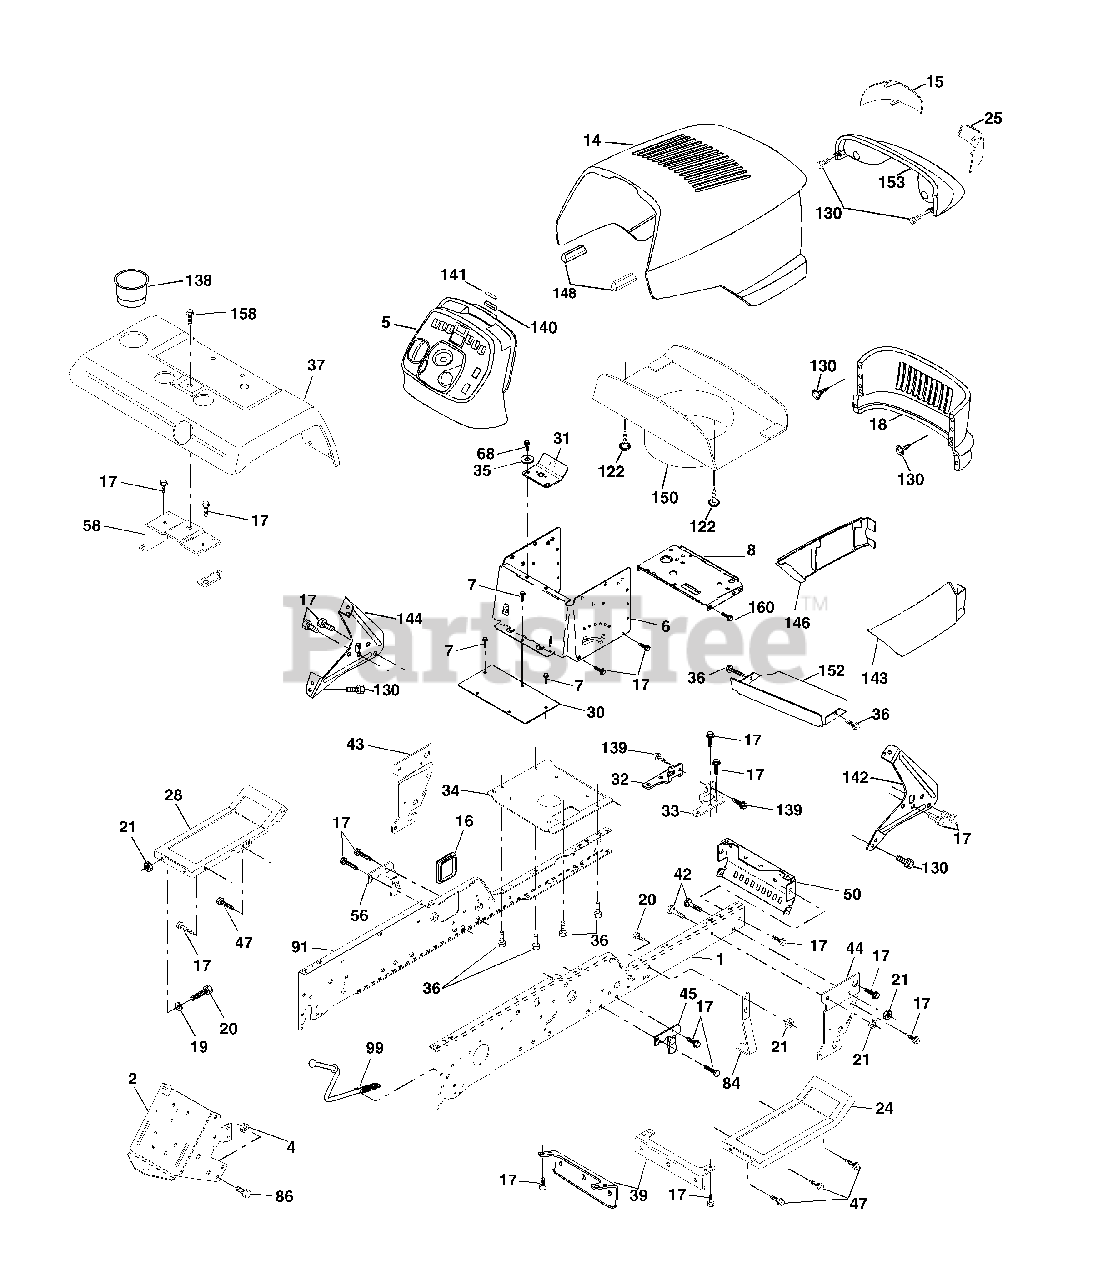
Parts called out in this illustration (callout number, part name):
1	Rail, Frame RH
2	Drawbar, Gt
4	Nut, Crown Lock 7/16-14 Unc
5	Dash, Plastic
6	Dash, 1PCS, Lower
7	Screw, Thd Cut 1/4-20 x 1/2
8	Support, Battery
14	Hood Asm., Pnt
15	Lens LH
16	Cover, Access
17	Screw, 3/8-16 x 3/4
18	Grille
19	Washer 13/32 x 13/16 x 12 Ga.
20	Bolt, Fin Hex 3/8-16 x 1
21	Nut, Lock Hex w/Ins. 3/8-16 Unc
24	Footrest, RH
25	Lens RH
28	Footrest, LH
31	Bracket Supt 1-pc Vgt Steering
32	Bracket, Frame Pivot Lh
33	Bracket, Frame Pivot Rh
34	Plate Asm Engine Chassis
35	Washer 11/32 x 11/16 x 16 Ga.
36	Screw 5/16-18 x 3/4
37	Fender, Pnt.
39	Bracket, Axle Front
42	Bolt Rdhd Sqnk 3/8-16 Unc x 1
43	Bracket, Spnsn Front Lh
44	Bracket, Spnsn Front Rh
45	Bracket Asm., Susp Chassis Rh
47	Screw Thdrol 3/8-16 x 1/2
50	Bracket, Chassis Front
56	Bracket Asm., Susp Chassis Lh
58	Bracket Asm., Fender
68	Screw, 5/16-18 x 1/2
84	Stop, Over Center Mower
86	Bolt, Fin Hex 7/16-14 Unc x 1
91	Rail, Frame Lh
99	Rod Asm. Bypass
122	Screw Hex WSHD 8-18 x 7/8
130	Screw Hw Hd Hi-Lo #13-16 x 3/4
138	Cupholder
139	Bolt Shoulder 5/16-18
140	Magnet Stealth
141	Striker Plate
142	Bracket Dash Stealth RH
143	Skirt Grille RH
144	Bracket Dash Stealth LH
146	Skirt Grille LH
148	Extrusion Bumper
150	Duct Heat Hood
152	Browning Shield
153	Lens Asm Headlht Dual
158	Screw Thdrol 3/8-16 x 1/2
160	Screw 5/16-18 x 1/2
